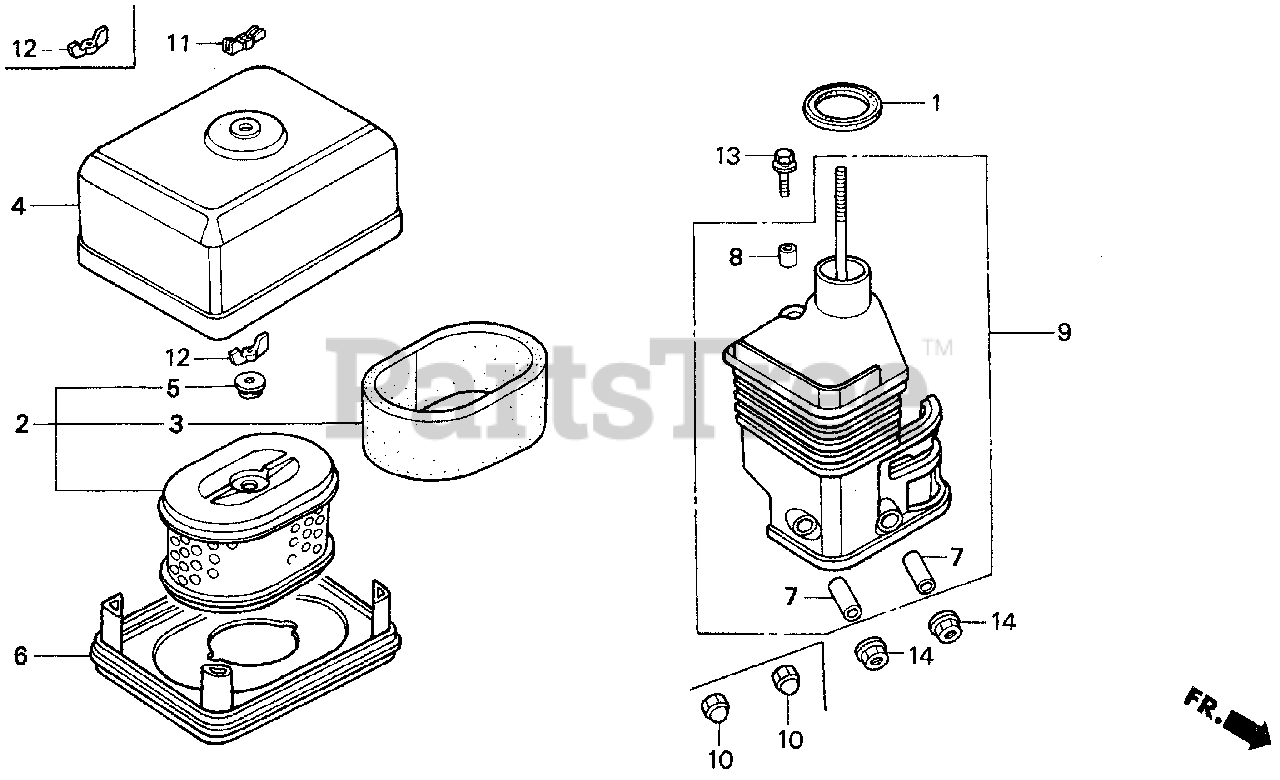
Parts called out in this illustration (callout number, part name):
1	GASKET, ELBOW
2	ELEMENT, AIR CLEANER (DUAL)
3	FILTER (OUTER)
4	COVER, AIR CLEANER (DUAL)
5	GROMMET, AIR CLEANER
7	COLLAR, AIR CLEANER
8	COLLAR B, AIR CLEANER
9	ELBOW, AIR CLEANER
10	NUT, CAP (6MM)
11	WINGNUT (6MM)
12	WINGNUT, TOOL BOX SETTING
13	BOLT-WASHER (6X20)
13	BOLT, FLANGE (6X20)
14	NUT, FLANGE (6MM)
